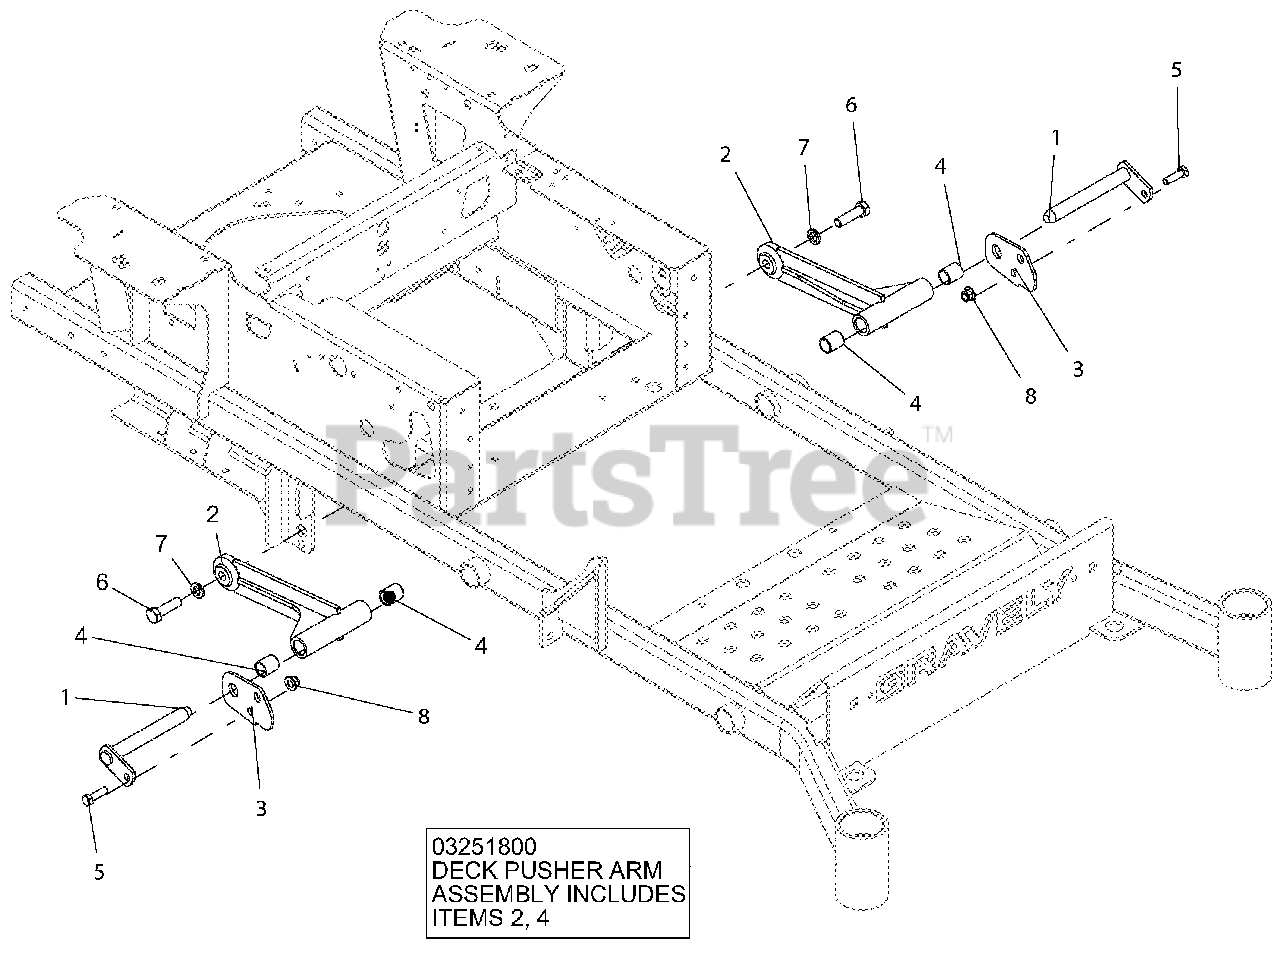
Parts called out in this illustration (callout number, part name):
1	WLDMT, MOWER MTG. PIN
2	DECK PUSHER ARM WLDMT - BLK
3	PLATE, PT REAR CHAIN MTG DOUBLER-RED
4	BRG, .75 X .875 X 1.00
5	BLT-HEX .38-16X1.25 GR5 YWZC
6	BLT-HEX .50-13X1.75 GR5 YWZC EP80
7	WSHR-LK .50X.125 REG YWZC
8	NUT-LK-NYL-FLG .38-16 YWZC
